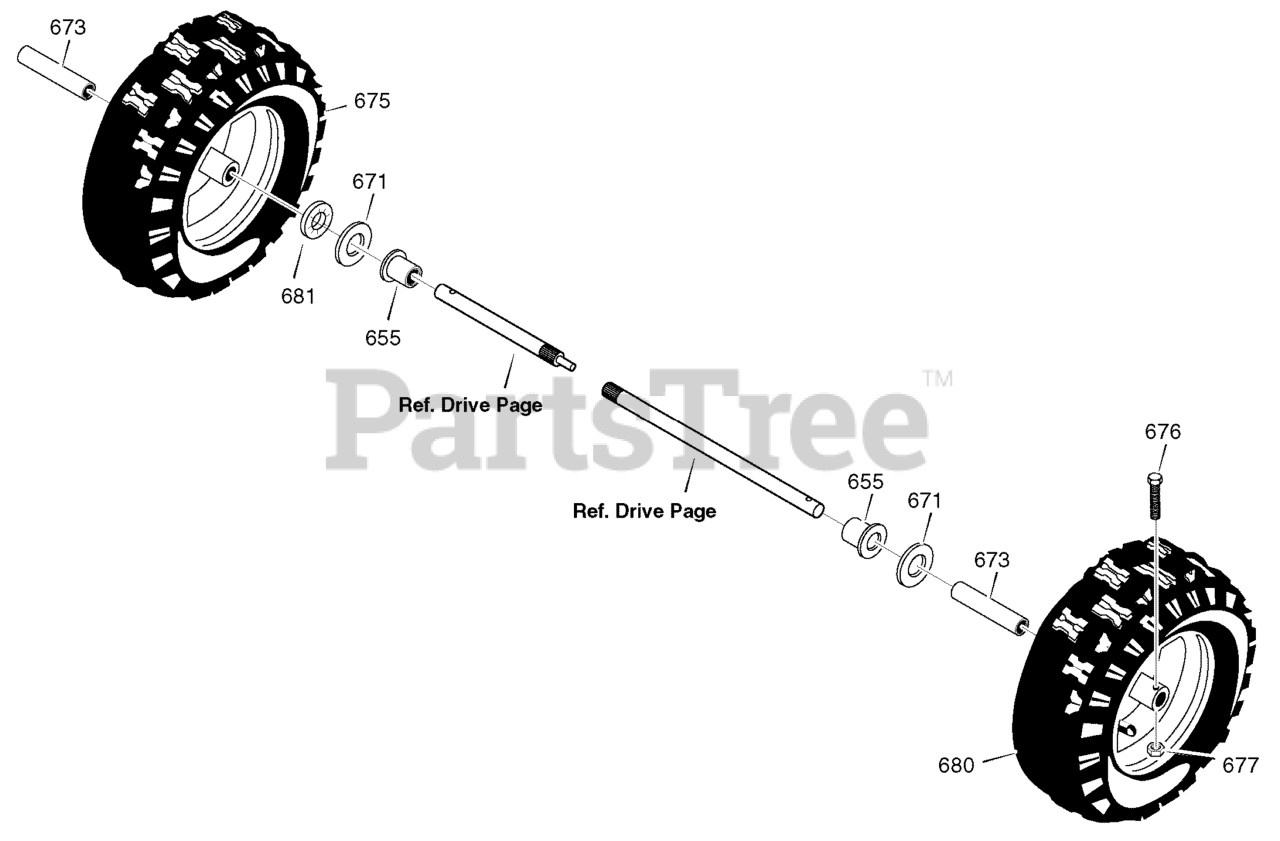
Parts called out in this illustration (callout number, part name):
655	BEARING, AXLE
671	FLATWASHER
673	BUSHING, WHEEL
675	TIRE & RIM, RIGHT
676	SCREW, 1/4-20X1.75 HH
677	NUT, 1/4-20 HEX NYLOCK
680	TIRE & RIM, LEFT
681	RETAINER
